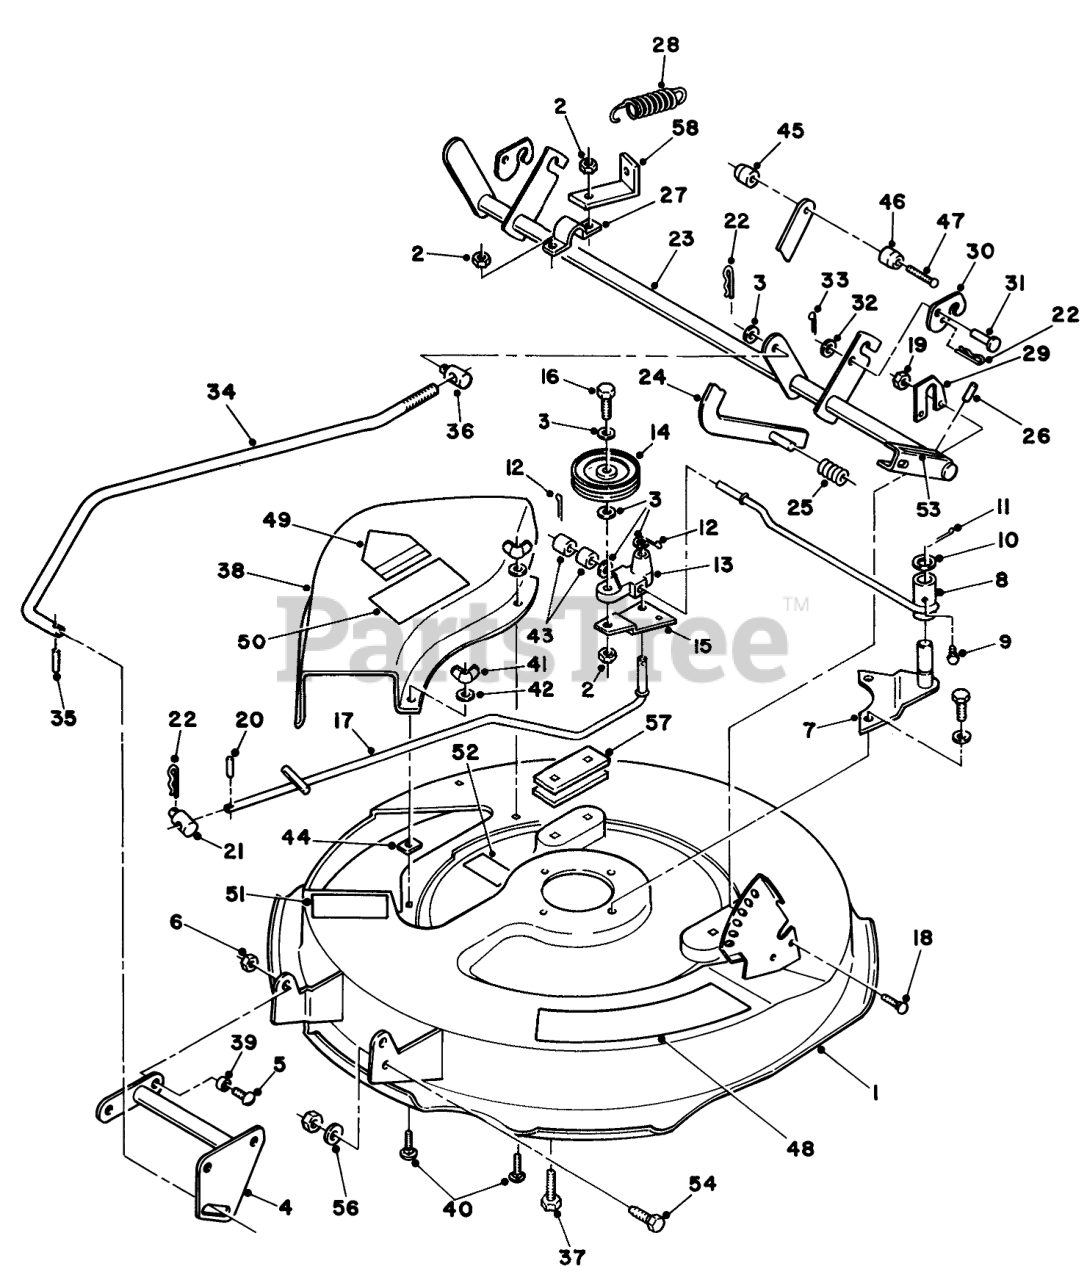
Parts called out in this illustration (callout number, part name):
1	ASM-DECK 30" L R
2	NUT-LOCK, NI
3	WASHER-FLAT
4	ASM-FRONT LIFT R
5	SCREW-CARR
6	LOCKNUT-FLANGE
7	ASM-PIVOT, IDLER
8	WLDMT-IDLER ROD
9	FITTING-GREASE
10	WASHER
11	PIN-COTTER
12	PIN-COTTER
13	BLOCK IDLER
14	PULLEY-IDLER V
15	ANCHOR-SPRING
16	SCREW-HH
17	ASS'Y-IDLER ROD
18	SCREW-CARR
19	NUT-LOCK, NI
20	PIN-SPRING
21	TRUNNION-LIFT
22	Hairpin Cotter
23	WLDMT-HT ADJ SHAFT R
24	WLDMT-LIFT LEVER R
25	SPRING-COMPRESSION
26	PIN-SPIROL
28	SPRING-EXTENSION
29	PLATE-RETAINER R
30	LATCH B
32	Washer
33	PIN-COTTER
34	ASS'Y-HEIGHT ADJ R
35	PIN-SPRING
36	STUD-TRUNION
37	BOLT-CARR
38	Deflector
39	SPACER
40	SCREW-CARR
41	WING NUT
42	WASHER
43	SPACER
44	SPEED NUT 1/4-20
45	KNOB
46	KNOB
47	BOLT-4
48	DECAL - DANGER
49	DECAL-DANGER
50	WASHER
51	DECAL-DANGER
52	DECAL-BELT ADJUST
53	DECAL-HOC
54	SCREW-HH
55	NUT-LOCK, NI
56	WASHER-FLAT
57	Bar
58	ANCHOR-SPRING B
